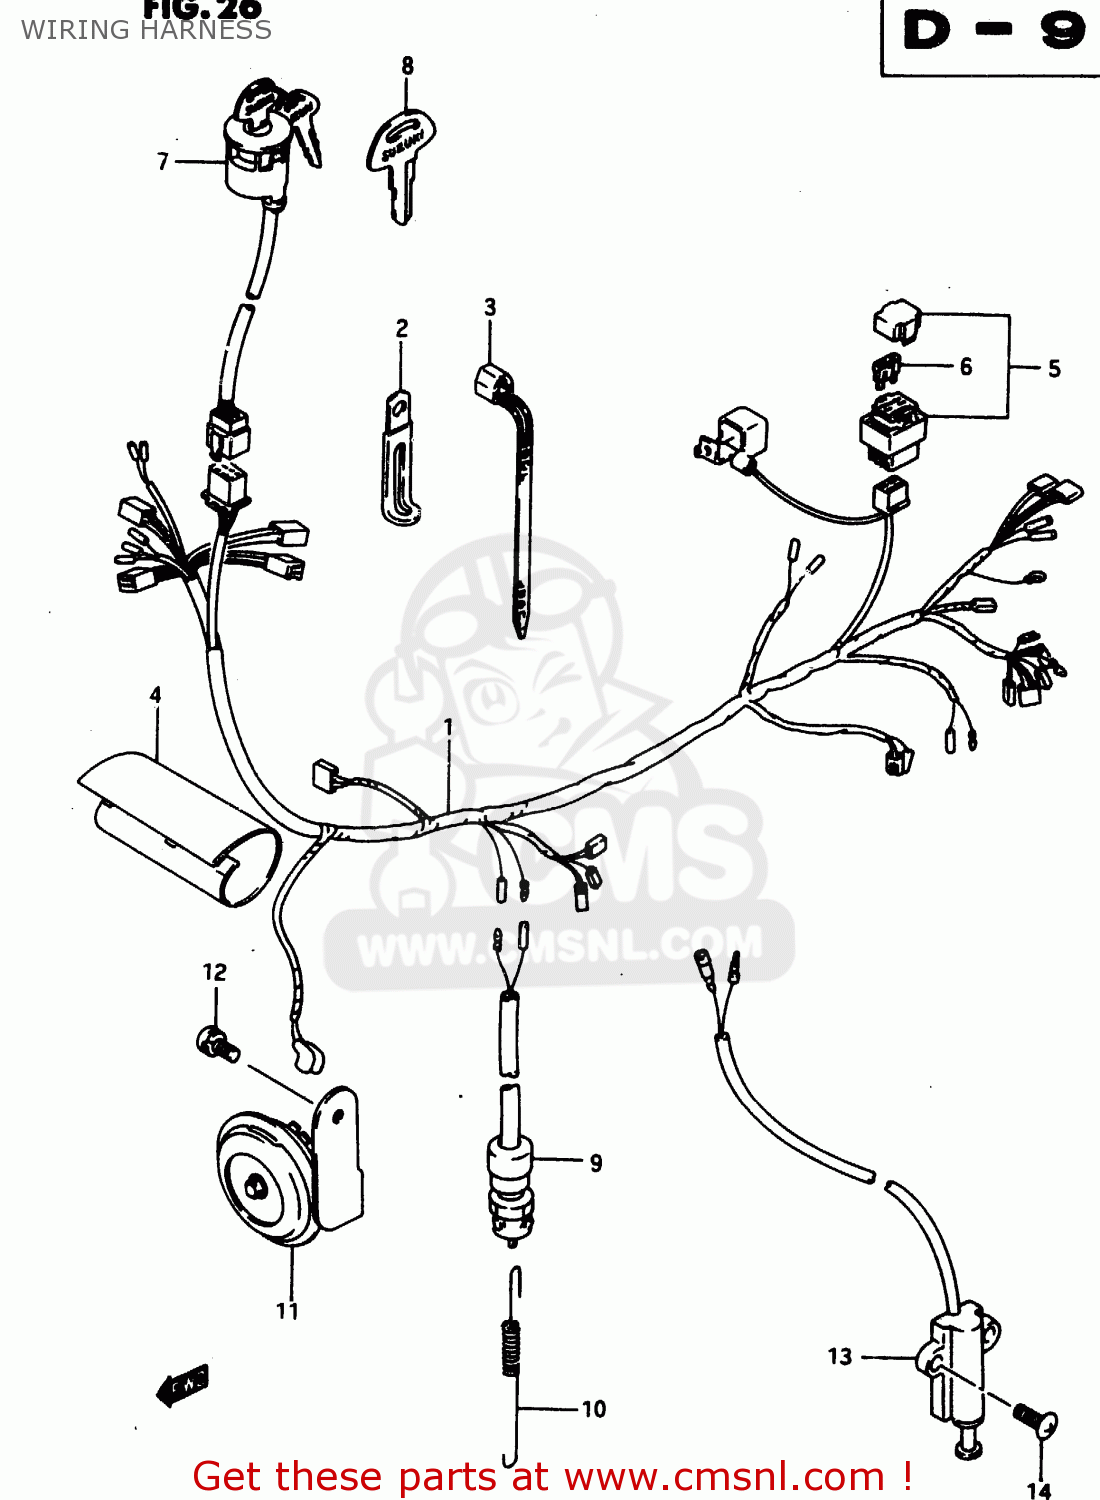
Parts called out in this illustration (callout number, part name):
1	HARNESS,WIRING
2	CLAMP
3	CLAMP(L:125)
4	COVER,WIRING HARNESS
5	BOX ASSY,FUSE
6	FUSE(15A)
7	SWITCH ASSEMBLY,IGNITION
8	KEY,BLANK
9	SWITCH ASSEMBLY,STOP LAMP
10	SPRING
11	HORN ASSY
12	SCREW
13	SWITCH ASSY,SIDE STAND WARNING
14	SCREW
